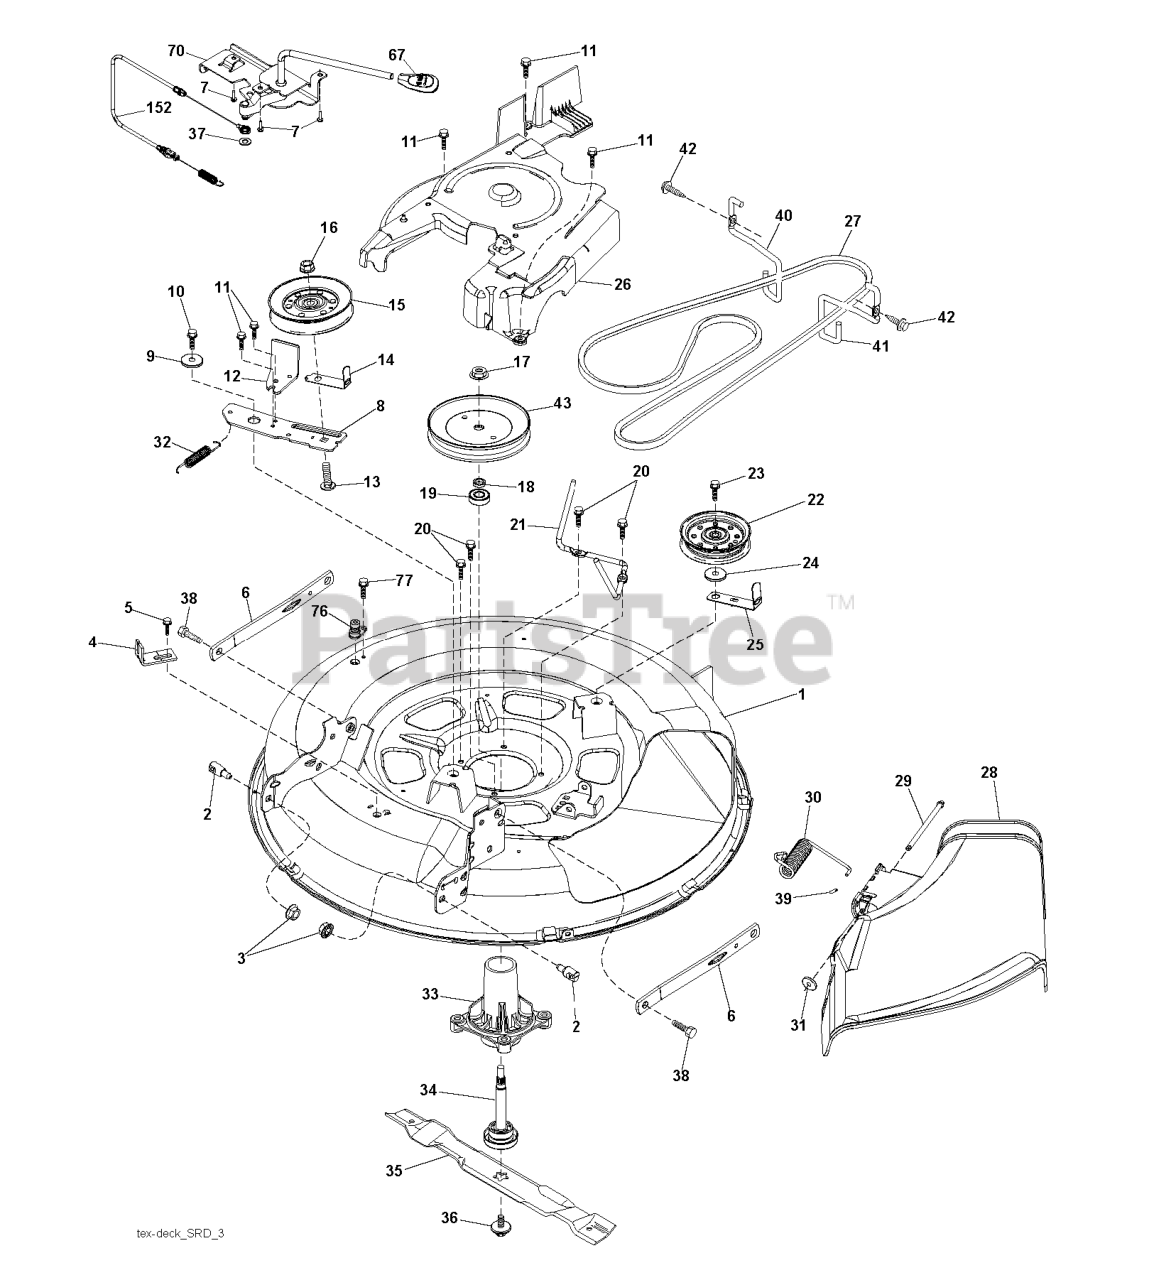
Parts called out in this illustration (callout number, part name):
1	DECK.WELDMENT.30".GREY
2	STUD.FASTNER.W/ANTI-ROTATE
3	NUT LOCK HEX FLANGE 5/16-18
4	BRACKET.CLUTCH.CABLE
5	BOLT.5/16HEX.WHS.HD
6	ARMS.SUSP.MOWER.REAR.SRD
7	SCREW.#10 X 0.750.BOS
8	ARM.IDLER.30"SRD
9	SPACER.RETAINER
10	SCREW 3/8-16X1
11	SCREW.1/4-20X5/8
12	RP ARM.BRAKE.MOWER.38"LH.TEX
13	BOLT.3/8-16X1.50
14	KEEPER, BELT IDLER
15	PULLEY.IDLER.4.25
16	NUT LOCK FLG 3/8-16 UNC
17	NUT.FLANGE.LOCK.TOP
18	WASHER.SPACER.MANDREL
20	SCREW, WASHER HEAD
21	KEEPER.BELT.MANDREL.30"
22	PULLEY.IDLER.FLAT.46.PR.DR.
23	SCREW LT
24	WASHER
25	KEEPER.BELT.30"SRD
26	COVER.ASM.MANDREL.30"
27	V-BELT.DRIVE.MOWER.30"
28	SHIELD.DEFLECT.MWR.30S.BLACK
29	PIN.HINGE.30".SRD
30	SPRING.TORSION.DEFLECT
31	NUT PUSH M
32	SPRING RETURN
33	RP.HOUSING.MANDREL.4PT.
34	SHAFT.ASM.MDRL.N/GREASE.38
35	BLADE, MULCH.LRV30
36	BOLT.WASHER.ASM.7/16-2
37	WASHER
38	BOLT.SHOULDER
39	CAP-SLEEVE LT
40	KEEPER.BELT.ENGINE.LH.LT.SRD
41	KEEPER.BELT.ENGINE.RH.LT.SRD
42	SCREW, 3/8-16X3/4
43	PULLEY, MANDREL 6.5 PD
67	HANDLE.CLUTCH.CABLE.LT
70	CLUTCH.ASM.MANUAL.LT.PRED
76	PORT.WASHOUT
77	SCREW.1/4-20X5/8
152	CLUTCH CABLE
